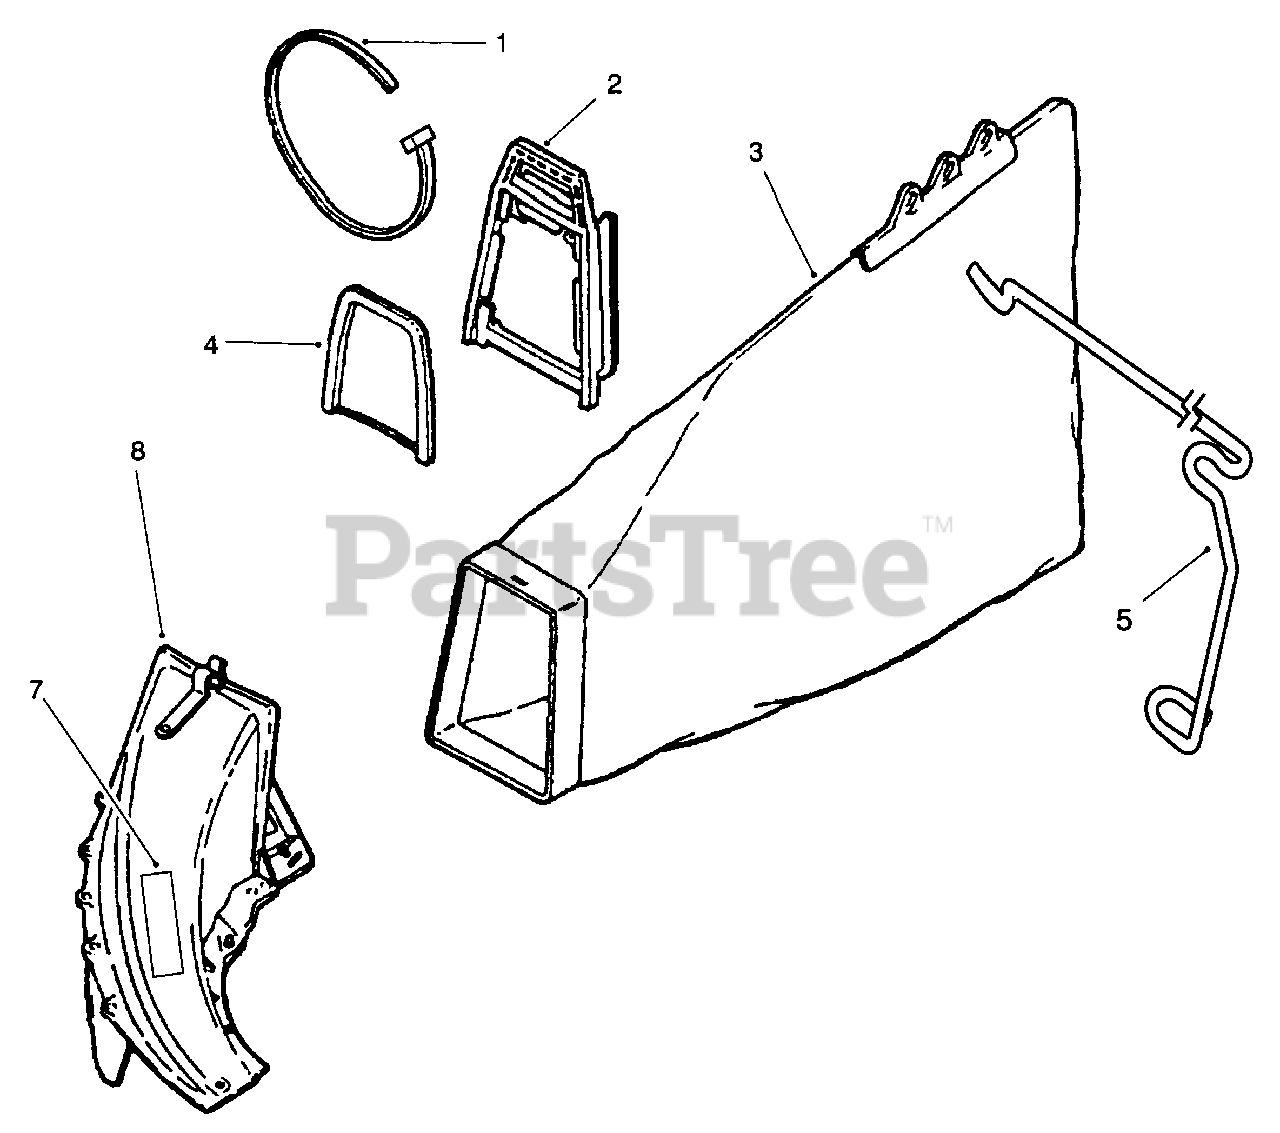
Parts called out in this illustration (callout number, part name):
1	Tie Strap
2	Adaptor-Chute
4	Brace-Chute
5	Rod-Grass Bag
7	Decal-Danger
8	Kit-Chute (Incl. Ref. #4) Used on 19" Supreme, 21" Steel or Cast Deck with Thru-Deck Discharge & 21" Supreme Mowers with Blade Brake Clutch.
